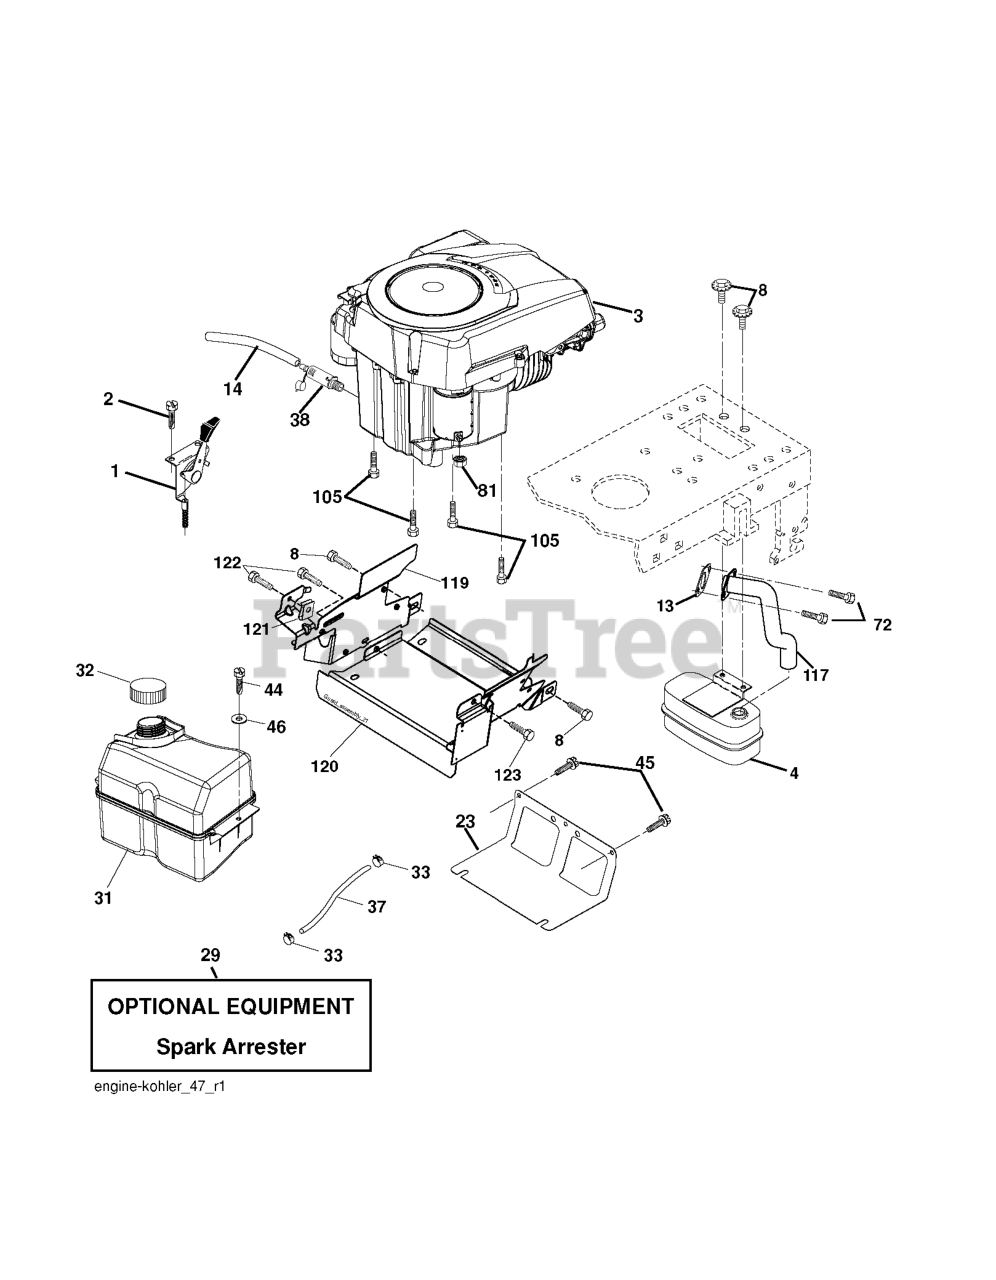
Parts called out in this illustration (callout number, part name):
1	CONTROL.TH/CK.C.
2	SCREW
4	MUFFLER.SINGLE.CYL.KOHL/B&S
8	BOLT.5/16-18UNCX3/4 W/SEMS.BLK
13	GASKET.EXHAUST.KOHLER
14	TUBE, DRAIN OIL ASM.
23	SHIELD.BROWNING.DBR.GUARD
29	KIT.SPARK ARRESTOR 794945 B&S
31	RP TANK FUEL FRT 1.5 GAL
32	FUEL CAP
33	HOSE CLAMP
37	LINE.FUEL.20
38	PLUG DRAIN OIL EASY
44	SCREW HEXWSHR 1/4-20X3/4
45	SCREW, 3/8-16X3/4
72	SCREW.SOCKET HD.5/16-1
81	NUT
105	SCREW 3/8-16X1
117	RP.TUBE.EXHAUST.KOHL.COURAGE
119	LENKRAD
120	GUARD 532199767
122	SCREW.1/4-20X5/8
123	SCREW, 5/16-18 X 1/2
